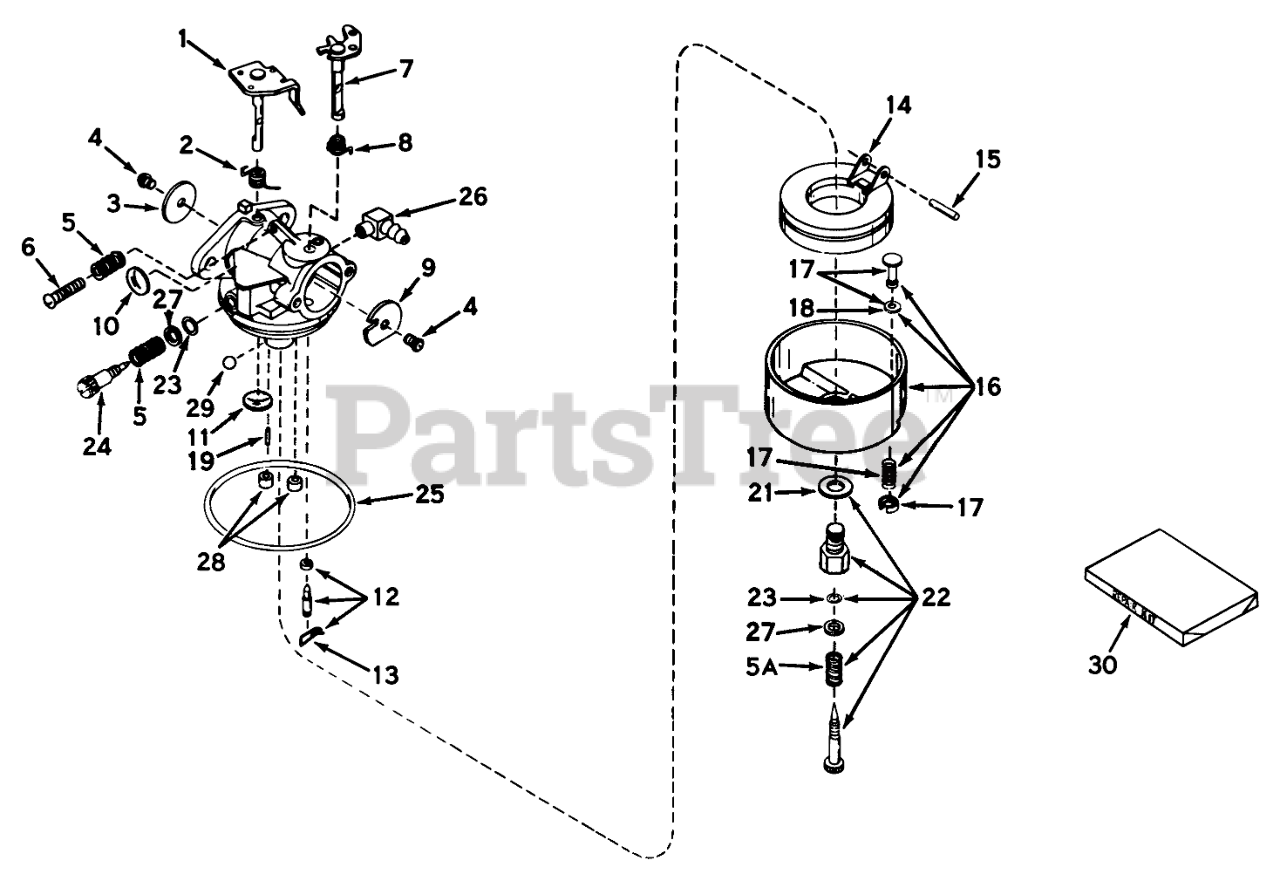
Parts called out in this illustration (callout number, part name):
1	Shaft & Lever Assy.
2	Spring, Throtte Return
3	Shutter-Throttle
4	Screw-Shutter
5	Spring-Tension
6	Screw-Throttle Crack Screw / Idle Speed
7	Shaft& Lever Assy., Choke
8	Spring, Choke return
9	Shutter, Choke
10	Plug-Welch, Idle Mixture Well
11	Plug-Welch, Atmospheric Vent
12	Inlet Needle, Seat & Clip Assy. (Incl. No. 13)
13	Clip-Spring
14	Float,Carburetor
15	Shaft-Float
16	Bowl & Drain., Float (Incl. No. 17)
17	Plug. Assy., Drain (Incl. #18)
18	Gasket-Plunger, Drain
21	Washer-Bowl Nut
22	Adj. Screw Assy., Main (Incl. Nos. 5A, 21, 23 & 27)
23	"O"RING, ADJUSTMENT SCREW
24	Screw, Idle Adj.
25	O Ring-Bowl, Float
26	Fitting Fuel Inlet
28	Plug, Cup
29	BalI, Steel
30	Repair Kit
